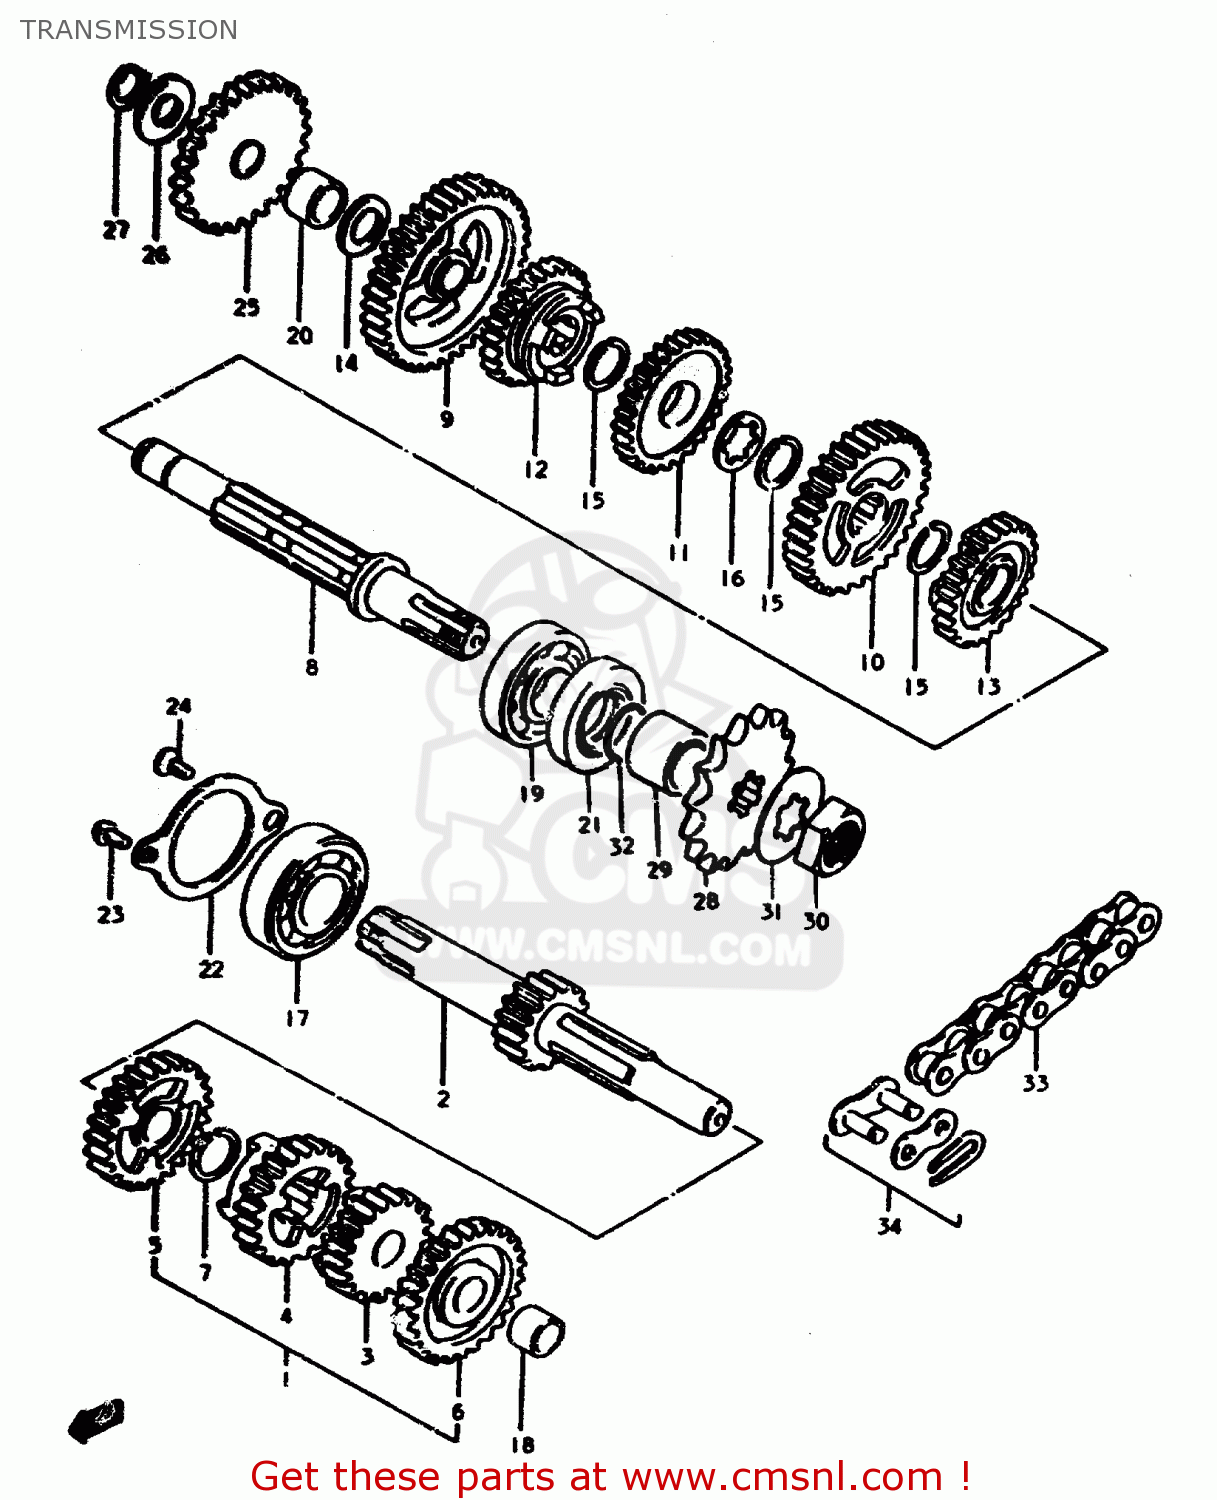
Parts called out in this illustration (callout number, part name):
1	SHAFT,COUNTER
2	SHAFT,COUNTER(NT:12)
3	GEAR,SECOND DRIVE
4	GEAR,THIRD DRIVE
5	GEAR,4TH DRIVE(NT:24)
6	GEAR,FIFTH DRIVE
7	CIRCLIP
8	DRIVESHAFT
9	GEAR,FIRST DRIVEN
10	GEAR,2ND DRIVEN(NT:33)
11	GEAR,3RD DRIVEN(NT:29)
12	GEAR,FOURTH DRIVEN
13	GEAR,5TH DRIVEN(NT:24)
14	WASHER(13X24X1)
15	CIRCLIP
16	WASHER,LOCK
17	BEARING
18	BUSH
19	BEARING
20	BUSH
21	SEAL,OIL(21X40X6)
22	RETAINER,CNTR SHAFT BEARING
23	SCREW
24	SCREW
25	GEAR,KICK STARTER IDLE
26	WASHER
27	CIRCLIP
28	SPROCKET,ENGINE
29	SPACER
30	NUT
31	LOCK WASHER
32	O RING(D:1,ID:16.8)
33	CHAIN ASSEMBLY,DRIVE
34	JOINT ASSEMBLY,CHAIN
